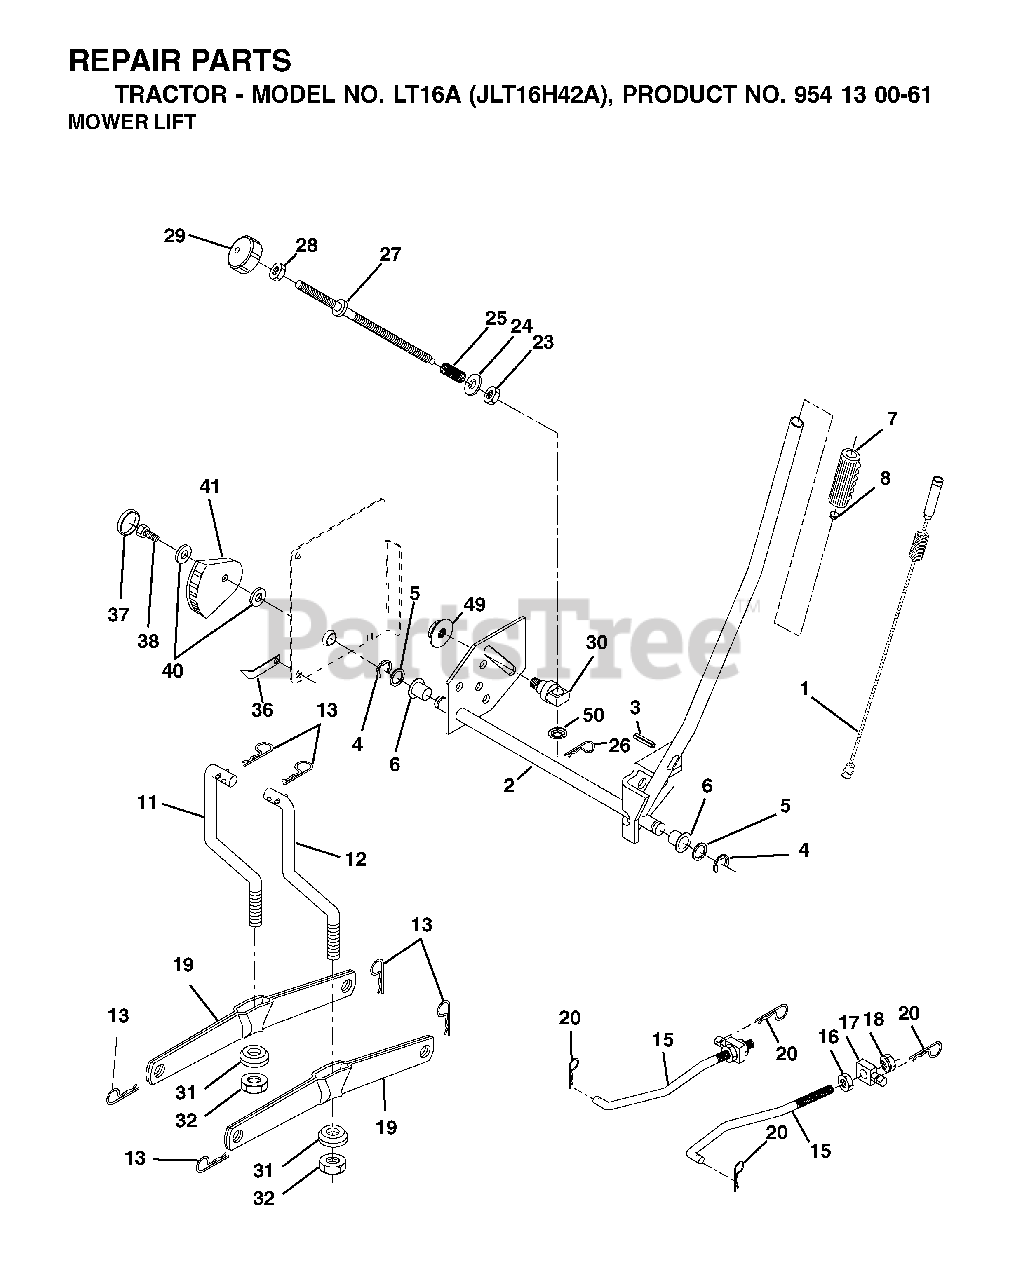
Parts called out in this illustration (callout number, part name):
1	WIRE ASM INNER W/ PLUNGER LT
2	SHAFT ASM R HANDLE
3	PIN GROOVE
4	RETAINING RING LT
6	BEARING.NYLON
7	GRIP HANDLE
11	LINK LIFT LH
12	LINK LIFT RH
13	RETAINER-SPRNG RB
15	LINK.SUSPENSION.FRONT
16	NUT
18	NUT
19	ARM.REAR.SUSPENSION
20	SPRING RETAINER
25	SPRING**
26	RETAINER CLIP
27	ROD ADJ LIFT
28	NUT
29	KNOB INF 3/8-16
31	BEARING.PIVOT.LIFT
32	NUT CROWNLOCK 3/8-24
36	POINTER, HEIGHT INDICATOR
37	PLUG,HOLE
38	SCREW 5/16-18X1
41	IND. HEIGHT STLT
49	NUT
50	NUT PUSH M
